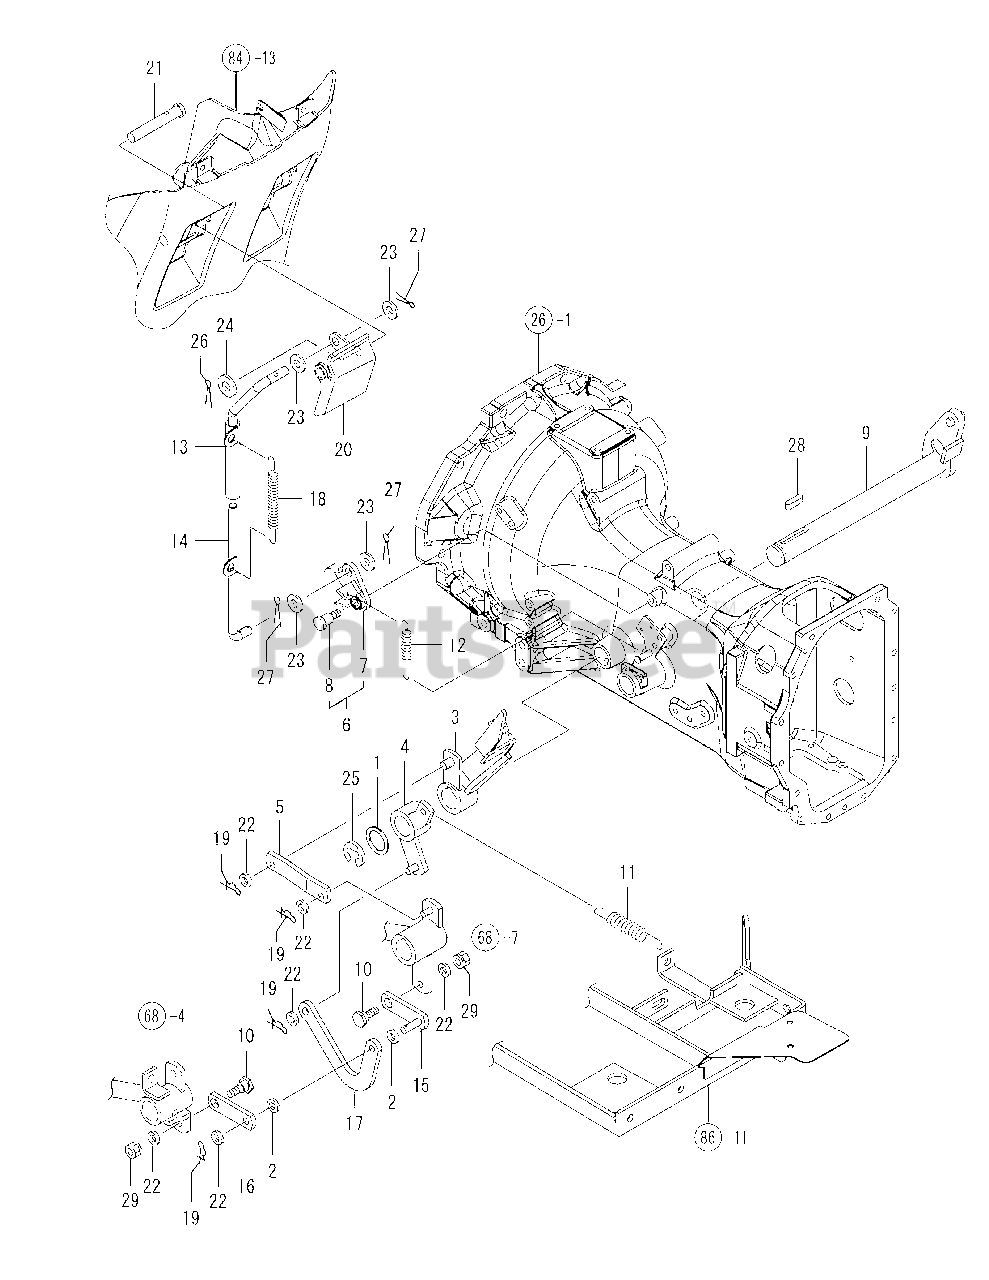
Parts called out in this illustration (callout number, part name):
1	Spacer 25.2X34X2
2	Washer 8.5X20X3.2
3	Arm Cmp, Parking
4	Arm Assy, Cruse
6	Rachet Kit,Park Lock
7	Rachet Cmp, Park Lock
9	Shaft Cmp, Cruise
11	Spring, Return
15	Link Cmp, Cruise
18	Spring, P.Brake
19	Pin 8, Come-Off Snap
20	Lever, P. Brake
22	Washer 8, Polished
23	Washer 10,Polished
24	Washer 12,Polished
26	Cotter Pin 2.0X32
27	Cotter Pin 2.5X25
